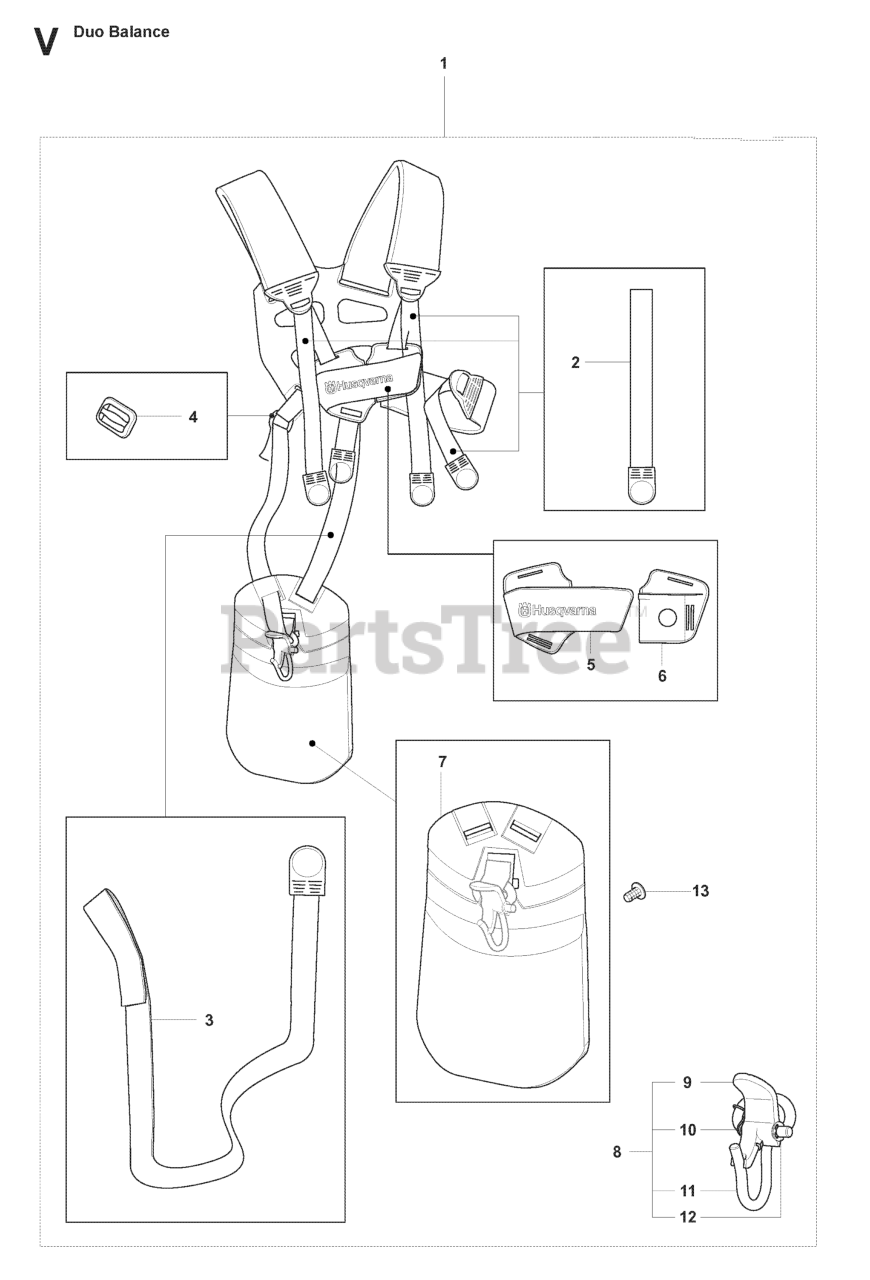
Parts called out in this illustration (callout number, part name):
1	Harness
1	Duo-Bal Harness
4	RP CLIP
5	FRONT PIECE
6	FRONT PIECE
8	HARNESS HOOK, COMPLETE
9	CATCH *
10	SPRING
11	HOOK
